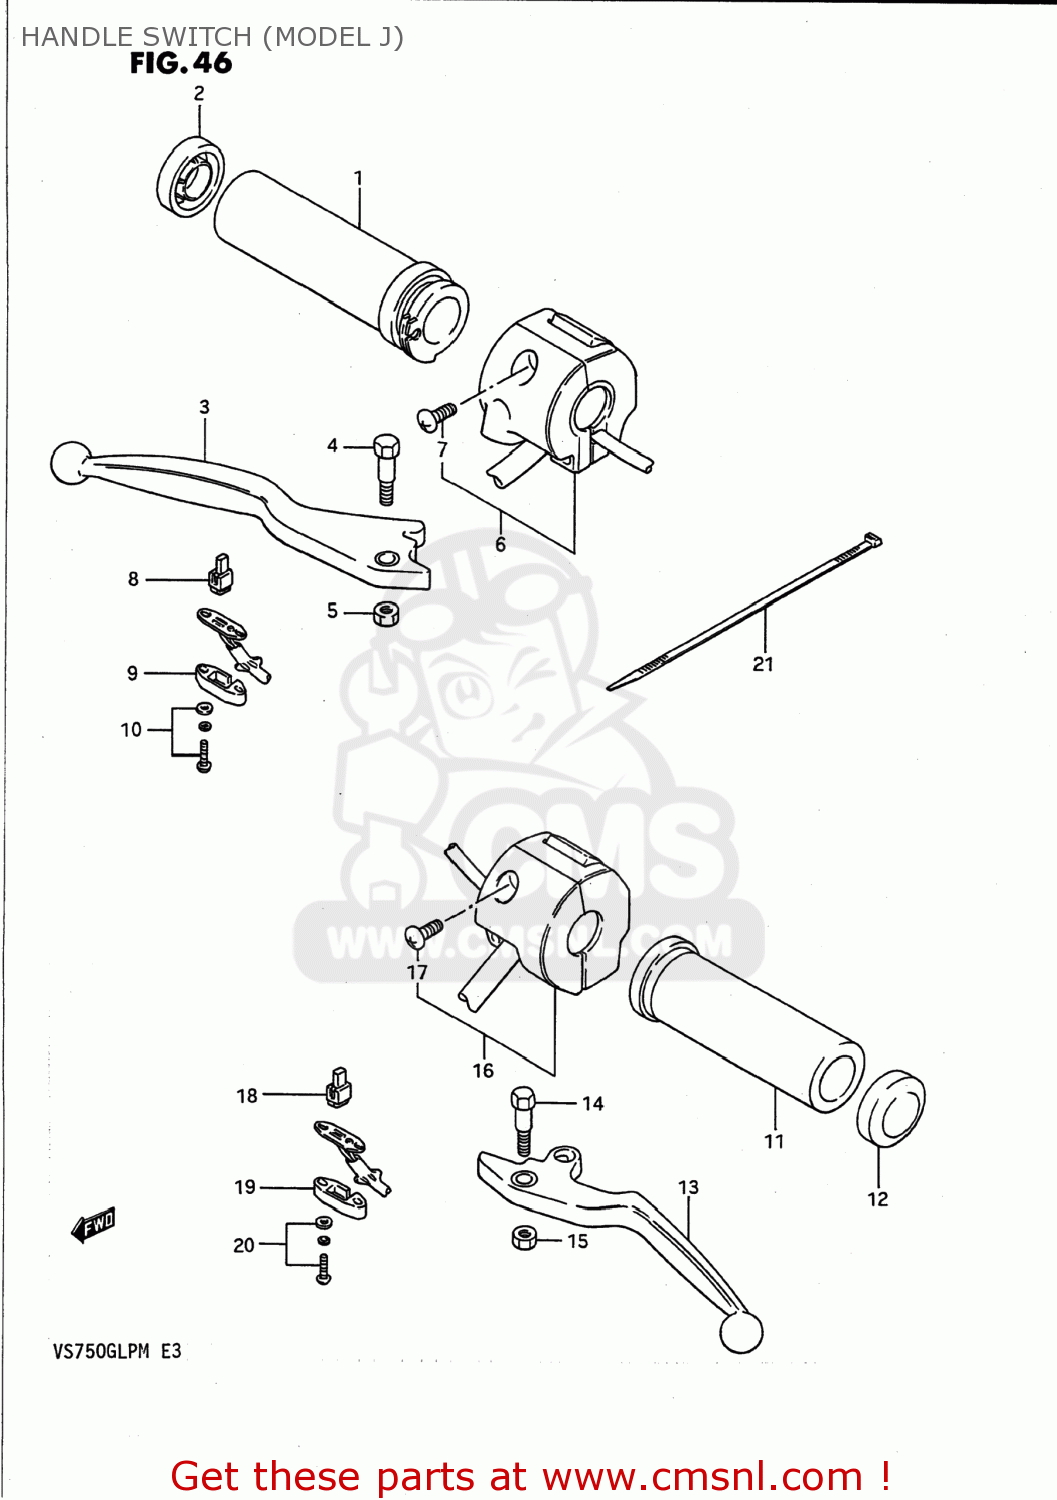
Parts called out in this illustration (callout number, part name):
1	GRIP,THROTTLE
2	CAP,GRIP END
3	LEVER,BRAKE
4	BOLT,LEVER
5	NUT 6MM
6	SWITCH ASSY,HANDLE,R
7	SCREW
8	CONTACT,SWITCH
9	COVER,BRAKE SWITCH
10	SCREW
11	GRIP,L
12	CAP,GRIP END
13	LEVER,CLUTCH (SILVER)
14	BOLT,LEVER
15	NUT 6MM
16	SWITCH ASSEMBLY,HANDLE,LEFT
17	SCREW
18	CONTACT,SWITCH
19	COVER,CLUTCH SWITCH
20	SCREW
